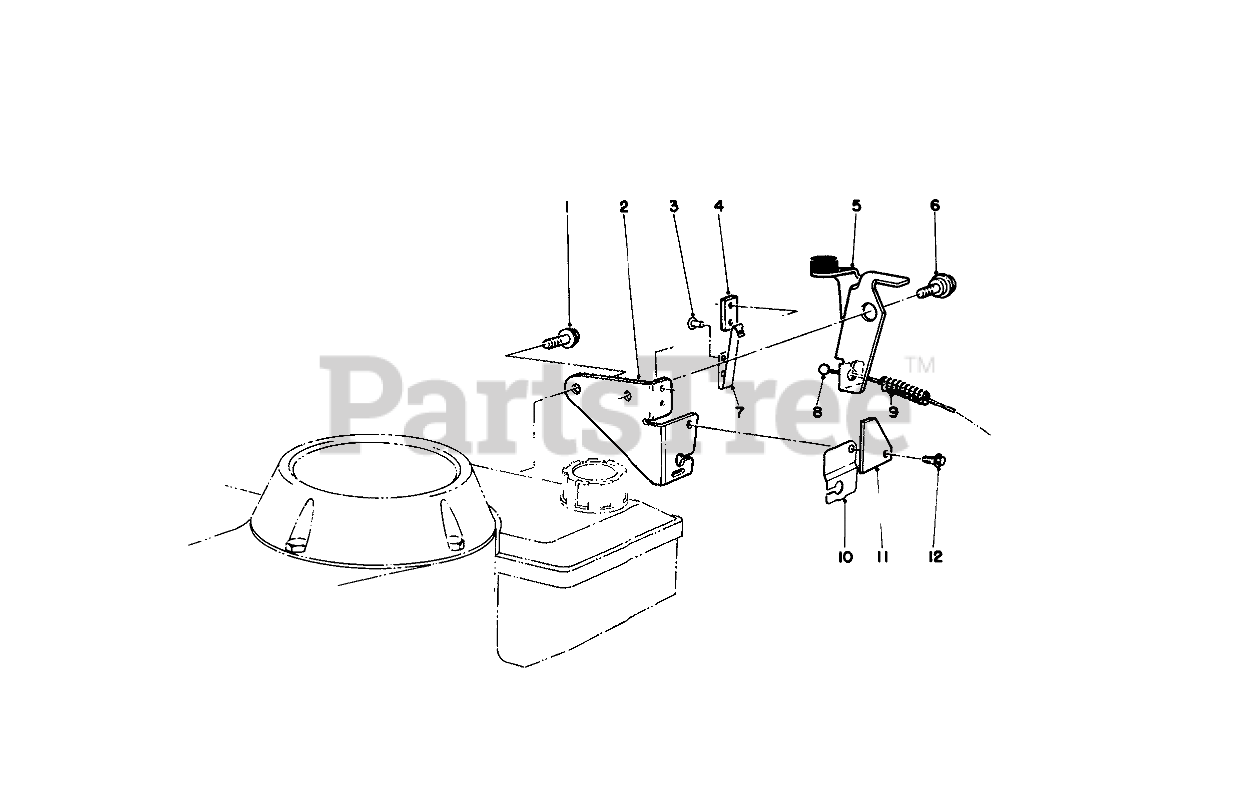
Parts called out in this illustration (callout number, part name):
1	THO FORM SCREW M6 X 1
2	Plate-Mounting Assembly (Incl. Ref. #3, 4 & 7)
3	RIVET-PLASTIC
4	Strap-Insulation
5	BRAKE PLATE ASM
6	POINT SET
7	STRAP-GROUND
8	BRAKE CABLE
9	SPRING-COMPRESSION
10	CABLE CLAMP
11	STOP-GROUND STRAP
12	SCREW
